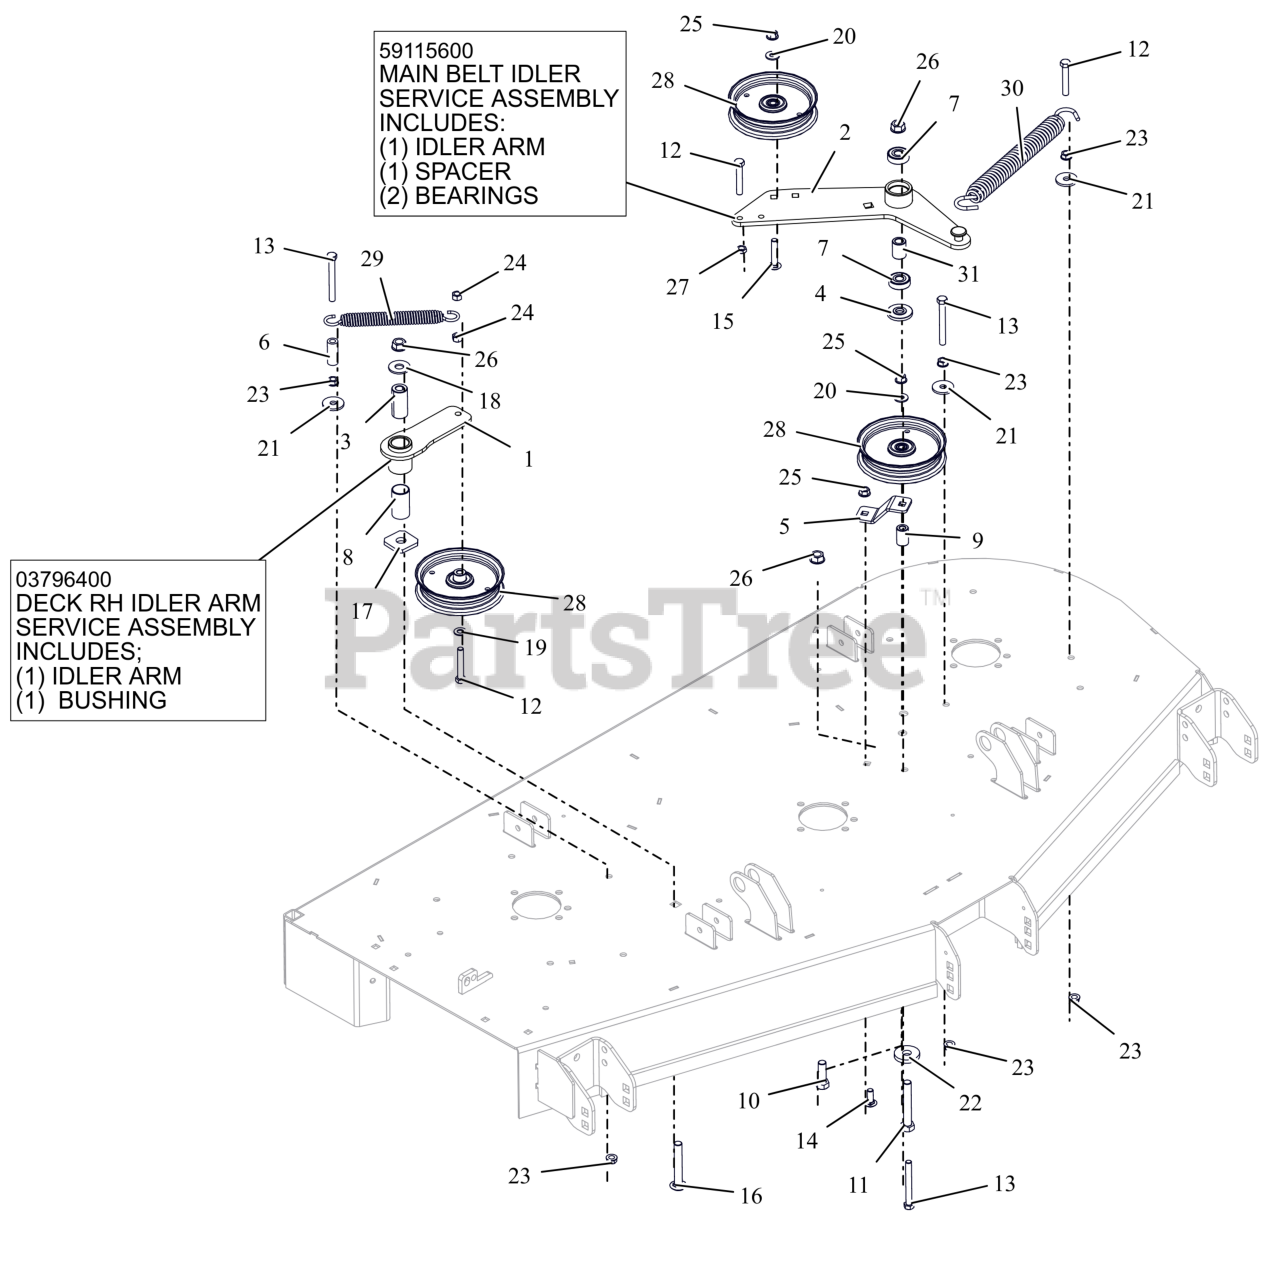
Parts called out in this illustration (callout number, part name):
1	WMT, IDLER ARM - BLACK
1	ASM, IDLER ARM (DECK)
2	WLDMT, DECK PTO IDLR ARM
2	ASSEMBLY, MAIN BELT IDLER
3	BSHG, SPCR .502X.997X2.03 PM
4	SPACER, IDLER ARM
5	PTO FIXED IDLER MTG BRKT-ORG
6	HOSE, .38 X 1.65
7	BRG-BALL .500X1.38X.437
8	BSHG, 1.00X1.125X1.937
9	BUSHING, SLV .380X.750X1.190
10	BLT,HEX .50-13X1.50 G5 ZCC
11	BLT,HEX .50-13X3.25 G5 ZCC
12	BLT,HEX .38-16X2.25 G5 ZCC
13	BLT, HEX .38-16X3.25 G5 ZCC
14	BLT,RHSSN .38-16X1.00 G5 ZCC
15	BLT,RHSSN.375-16X2.00 G5 ZCC
16	BTL,RHSSN .500-13 X 3.25 G5 ZCC
17	WSHR-FLT .640X1.75X.250
18	WSHR,FLT .563X1.375X.109 ZCC
19	WSHR,FLT .406X.812X.065 ZCC
20	WSHR,FLT .375X.875X.083 ZCC
21	WSHR,FLT .406X1.375X.135 ZCC
22	WSHR-FL-STL 0.557X1.625X0.25 ZCC
23	NUT, SPNLK-FLG .38-16 G5 ZCC
24	NUT-LK-CTR .38-16 ZC120
25	NUT-LK-CTR-FLG .375-16 GF ZCC
26	NUT-LK-CTR-FLG .500-13 GG ZCC
27	NUT-JAM .375-16 G2 ZCC
28	IDLER- FLAT - 5.00" X .75"
29	SPRING, EXTENSION
30	SPRING, EXTENSION
31	SPACER .510 X .867 X 1.1485
